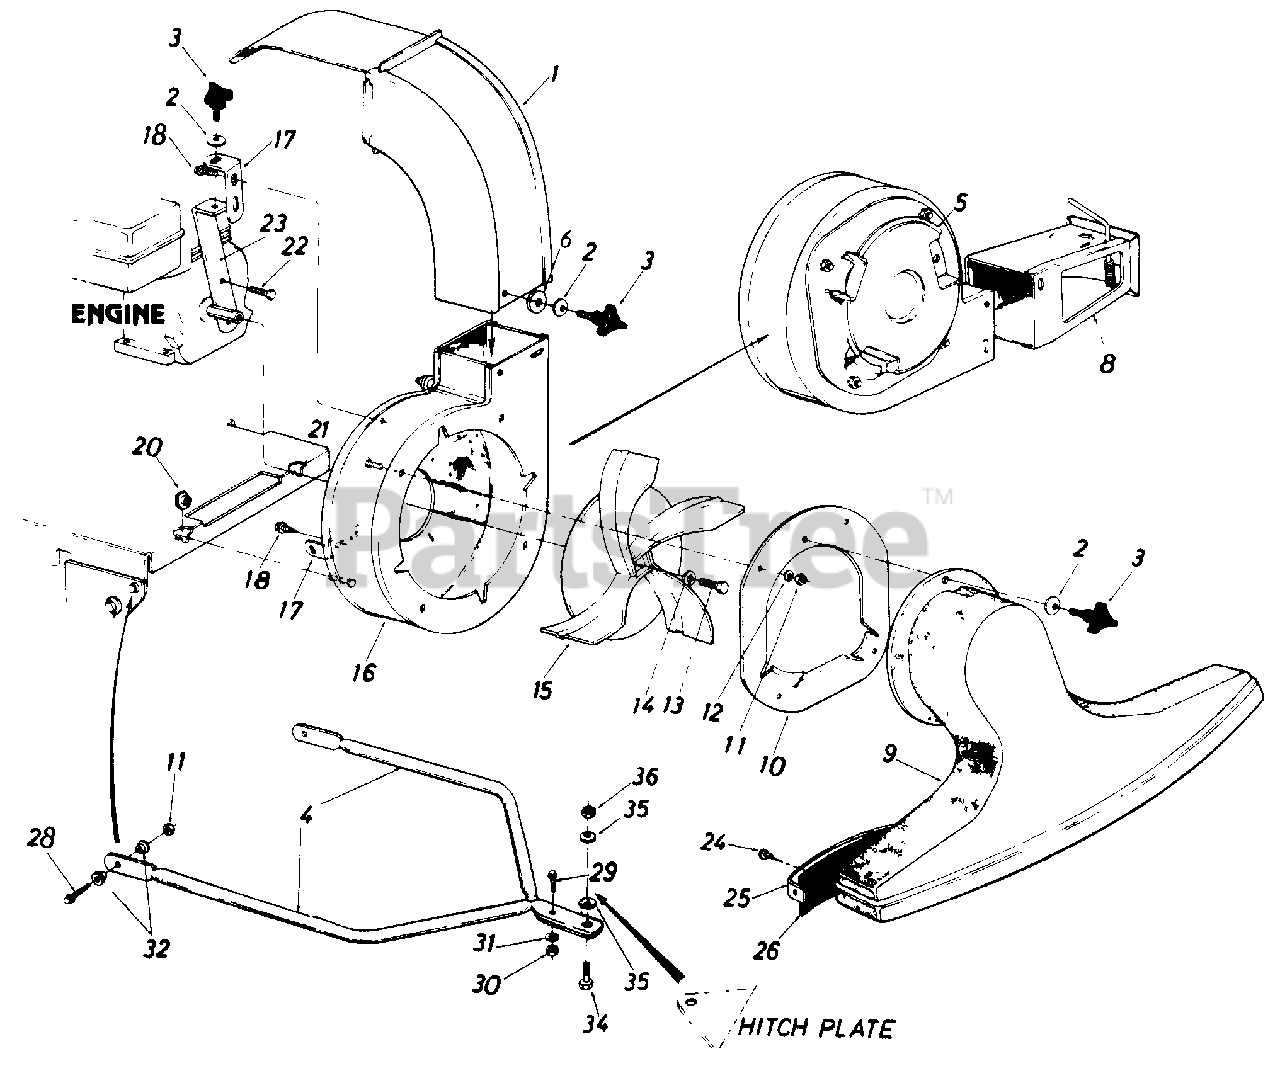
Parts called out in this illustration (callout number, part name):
3	Hand Knob
6	Fl-Wash. .344" I.D. x 1.125" O.D.
10	Nozzle Plate Ass'y.
11	Hex Nut 5/16-18 Thd.
12	L-Wash. 5/16" I.D.
13	Hex Bolt 3/8-24 x 1.25" Lg.
14	L-Wash. 3/8" I.D. H.D.
15	Air Vane Plate Ass'y.
20	Hex Shoulder Nut .50 I.D.
21	Carriage Bolt 5/16-18 x .62"
22	Hex Locking Bolt 5/16-24 x .75" Lg.
28	Hex Bolt 5/16-18 X 1.00 Lg.
29	Truss Mach. Scr. 1/4-20 x .75
30	Hex Nut 1/4-20 Thd.
31	L-Wash. 1/4 I.D.
32	Shoulder Spacer
34	Shld. Bolt .496 Dia.
35	Belleville Wash. .39" I.D. x 1.12" O.D.
36	Hex Jam L-Nut 3/8-26 Thd.
